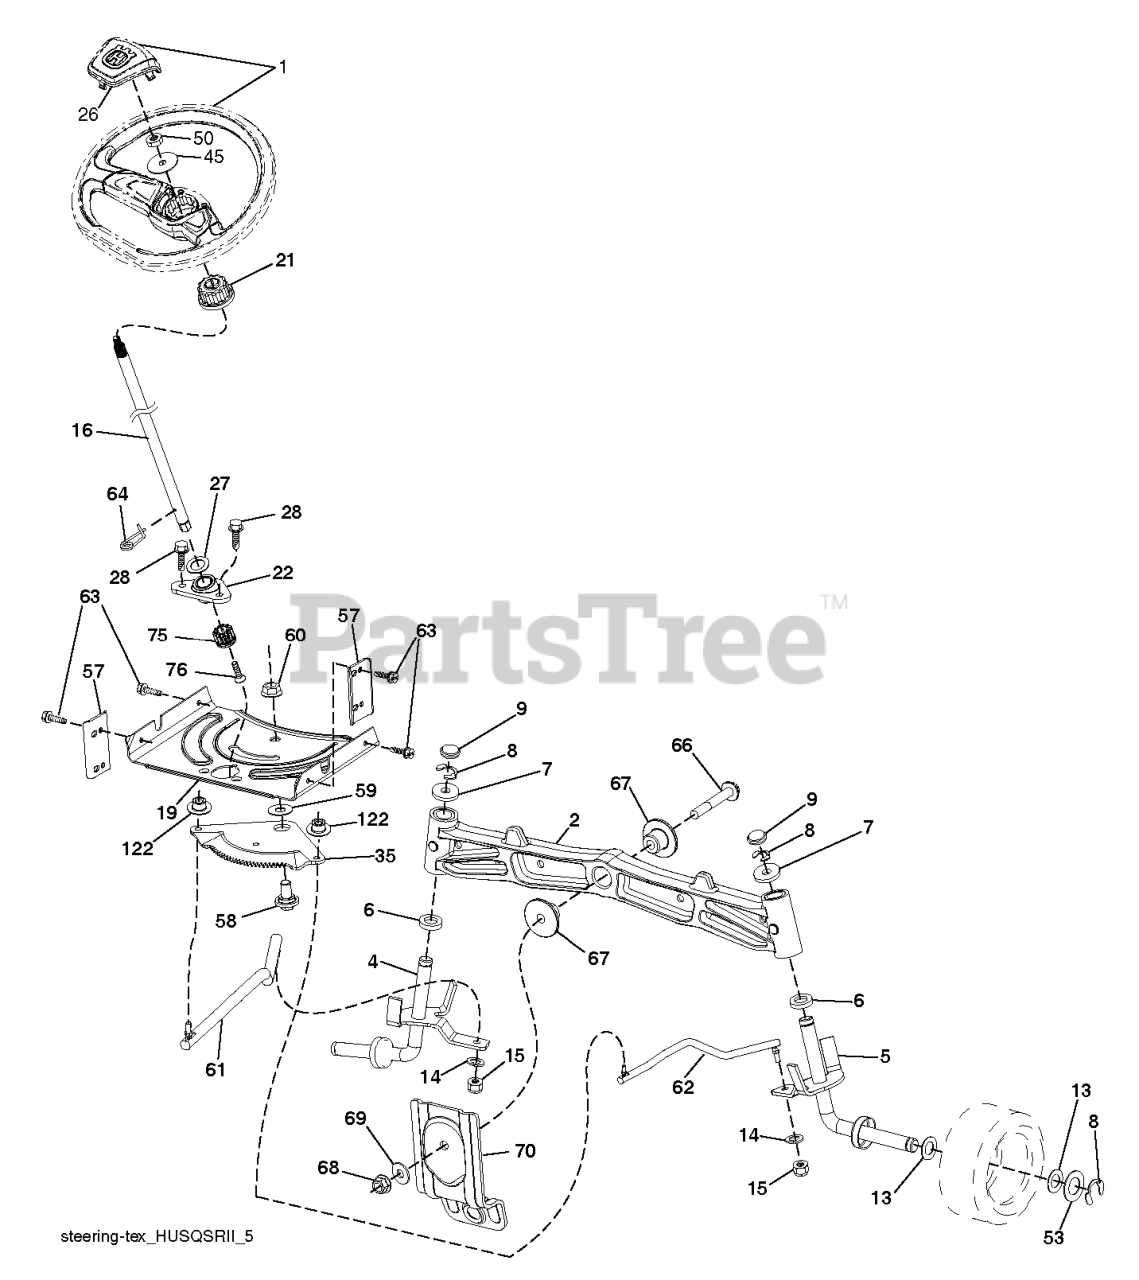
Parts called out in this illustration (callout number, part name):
1	Service Kit
2	AXLE.CAST.IRON
4	SPINDLE.WELDED.LH.15"TEX
5	SPINDLE.WELDED.RH.15"T
6	WASHER THRUST
9	CAP.SPINDLE.BLACK
15	NUT CROWNLOCK 3/8-24
16	SHAFT.STEER.2HIGH.SPLND.PLATED
19	PLATE.STEER.DDL.NLT/NG
21	ADAPTER.WHEEL.STEER.SPLND.ALUM
22	BEARING.SHAFT.STEER.LOWER.625
28	SCREW, 3/8-16X3/4
35	GEAR.SECTOR.PLATE.DDL.
45	WASHER.3/8ID.2-3/8OD.12GA.PLTD
50	NUT LOCK FLG 3/8-16 UNC
53	WASHER.HARDENED
57	BRACKET.UPSTOP.TEX
58	BOLT.SHOULDER.SECTOR.P
59	WASHER.THURST.SECTOR.S
60	NUT FLANGE LOCK 5/8-11
61	Links
62	Links
63	SCREW
64	RETAINER.CLIP.SPRING.S
66	BOLT HEX FGHD 7/16-14 X 3 SERR
67	BUSHING.PM.FRONT AXLE
68	NUT.LOCK.FLANGE.7/16
69	WASHER.1.5X.505X.118
70	BRACKET.FRT.DECK.SUSP.RR.MT431
75	PINION.ZINC PLATED
76	SCREW HEAD SOCKET LRVB
122	CAP.GEAR.SECTOR.TEX
